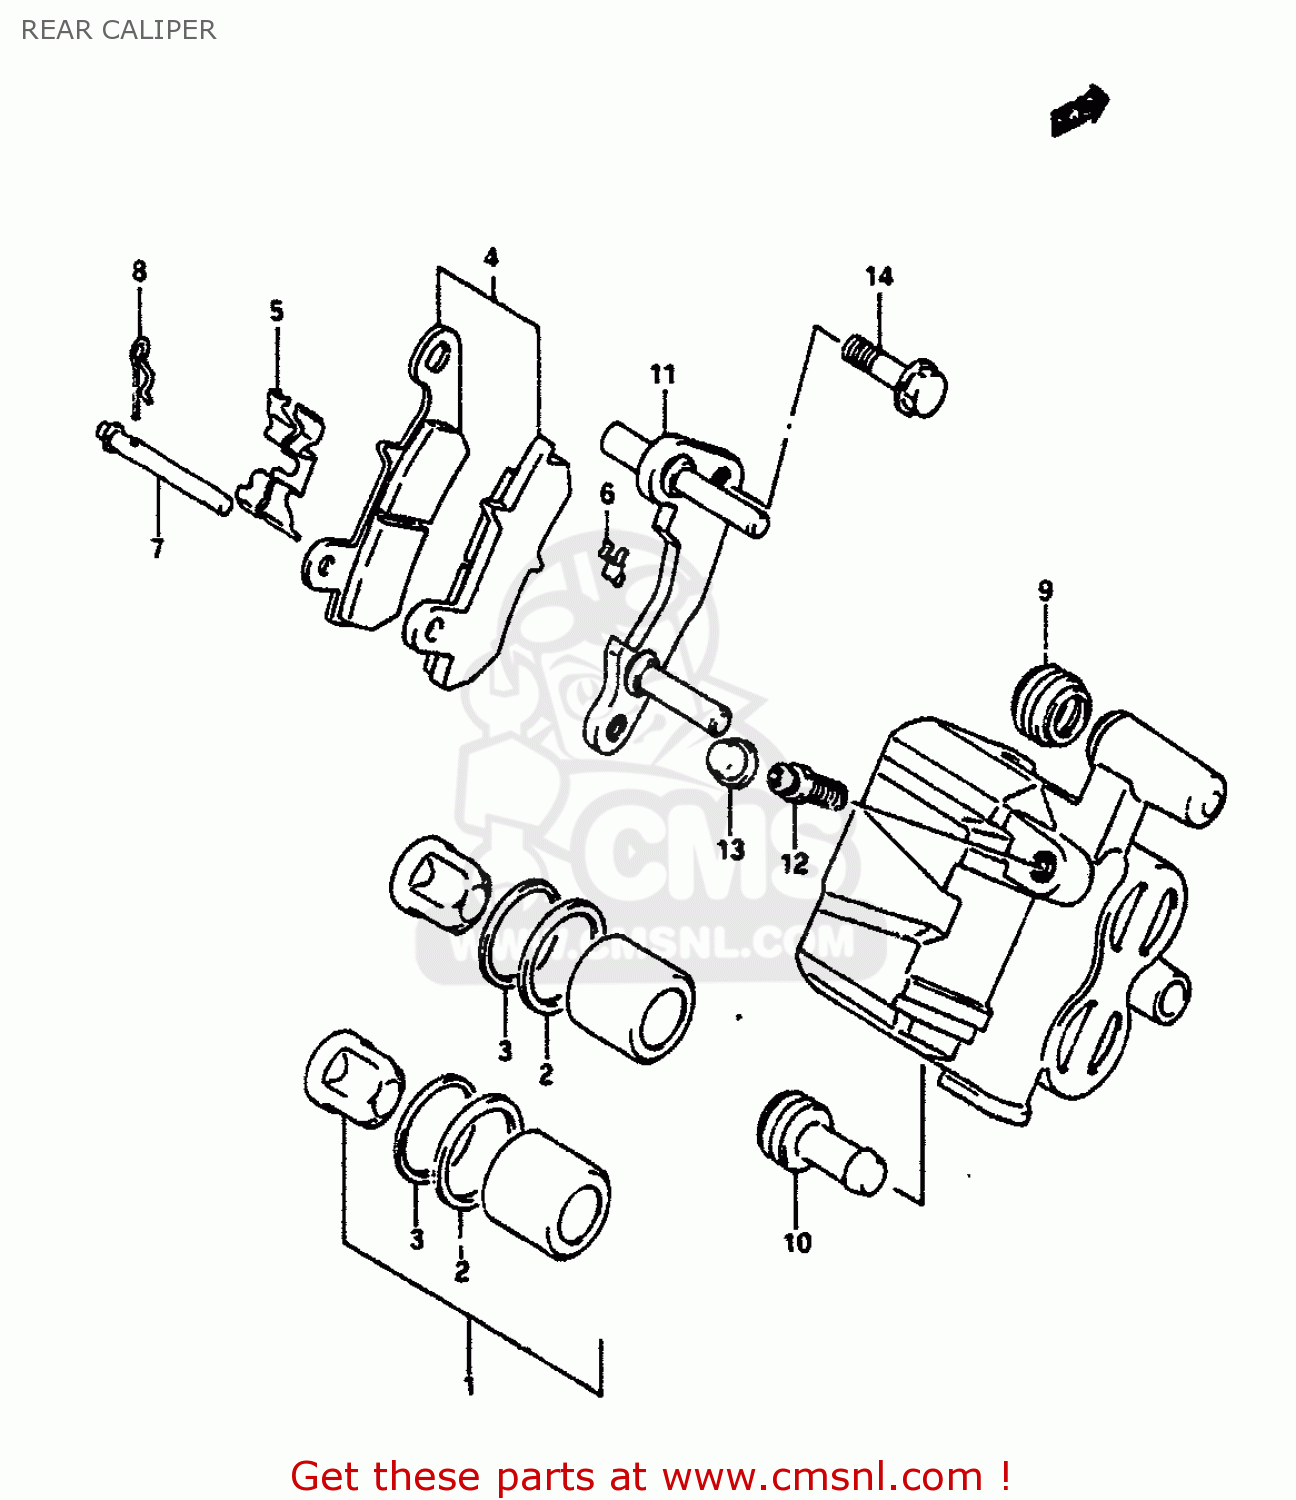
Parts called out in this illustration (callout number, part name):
1	BRAKE PISTON SET
2	SEAL,PISTON
3	SEAL,WIPER
4	PAD SET (NAS)
5	SPRING,PAD
6	GUIDE,PAD
7	PIN,PAD
8	CLIP,PAD PIN
9	BOOT,AXLE
10	INSULATOR,AXLE
11	CARRIER
12	BLEEDER
13	CAP,BREATHER
14	BOLT(8X22)
